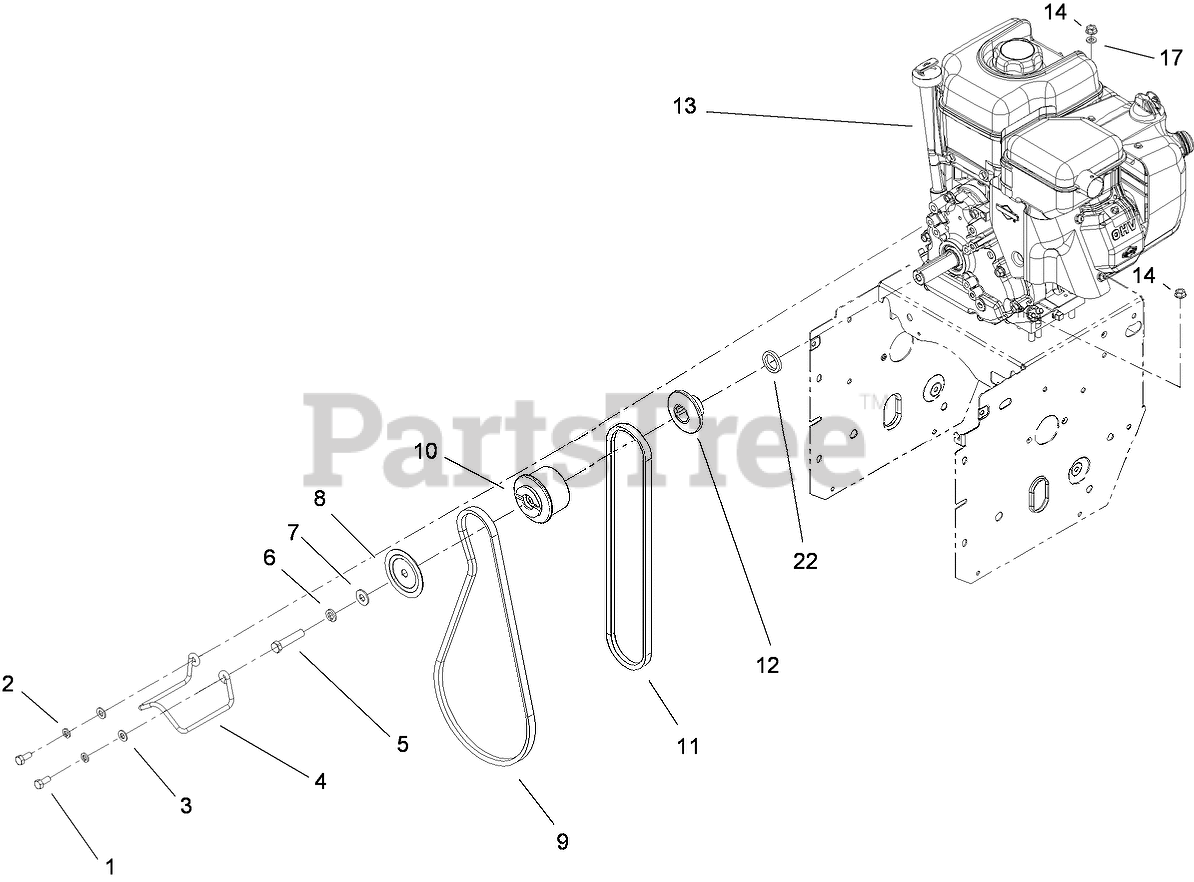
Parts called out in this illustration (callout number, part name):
1	SCREW-HH
2	WASHER-LOCK
3	WASHER-PLAIN
4	GUIDE-BELT
5	SCREW-HH
6	WASHER-LOCK
7	WASHER-FLAT
8	SHEAVE-HALF, IMPELLER
9	BELT-V
10	PULLEY-ENGINE, CENTER
11	V BELT-TRACTION
12	SHEAVE-HALF, TRACTION
14	NUT-HF
17	WASHER-FLAT
22	SPACER-HARDENED
